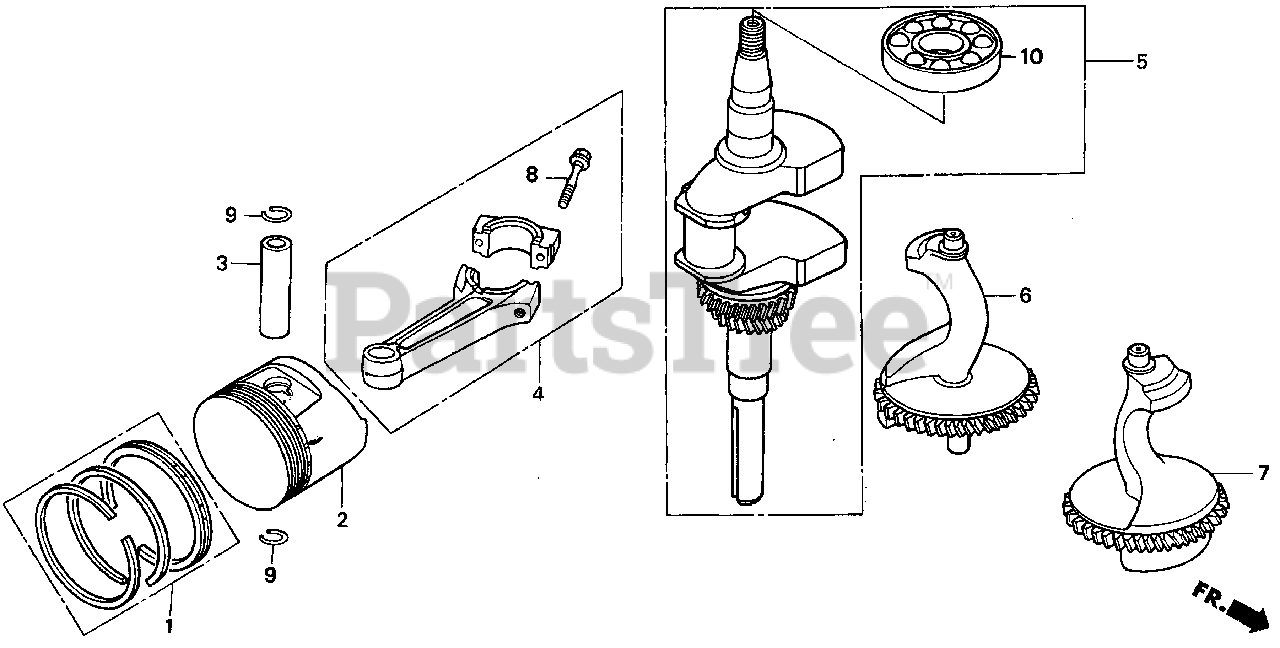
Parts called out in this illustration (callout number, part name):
1	RING SET, PISTON (STD)
1	RING SET, PISTON (OS 0.25)
1	RING SET, PISTON (OS 0.50)
1	RING SET, PISTON (0.75)
2	PISTON (STD)
2	PISTON (OS 0.25)
2	PISTON (OS 0.50)
2	PISTON (0.75)
3	PIN, PISTON
4	ROD ASSY., CONNECTING
4	ROD ASSY., CONNECTING (US 0.25)
5	CRANKSHAFT
6	WEIGHT A, BALANCER
7	WEIGHT B, BALANCER
8	BOLT, CONNECTING ROD
9	CLIP, PISTON PIN (20MM)
10	BEARING, RADIAL BALL (6207)
